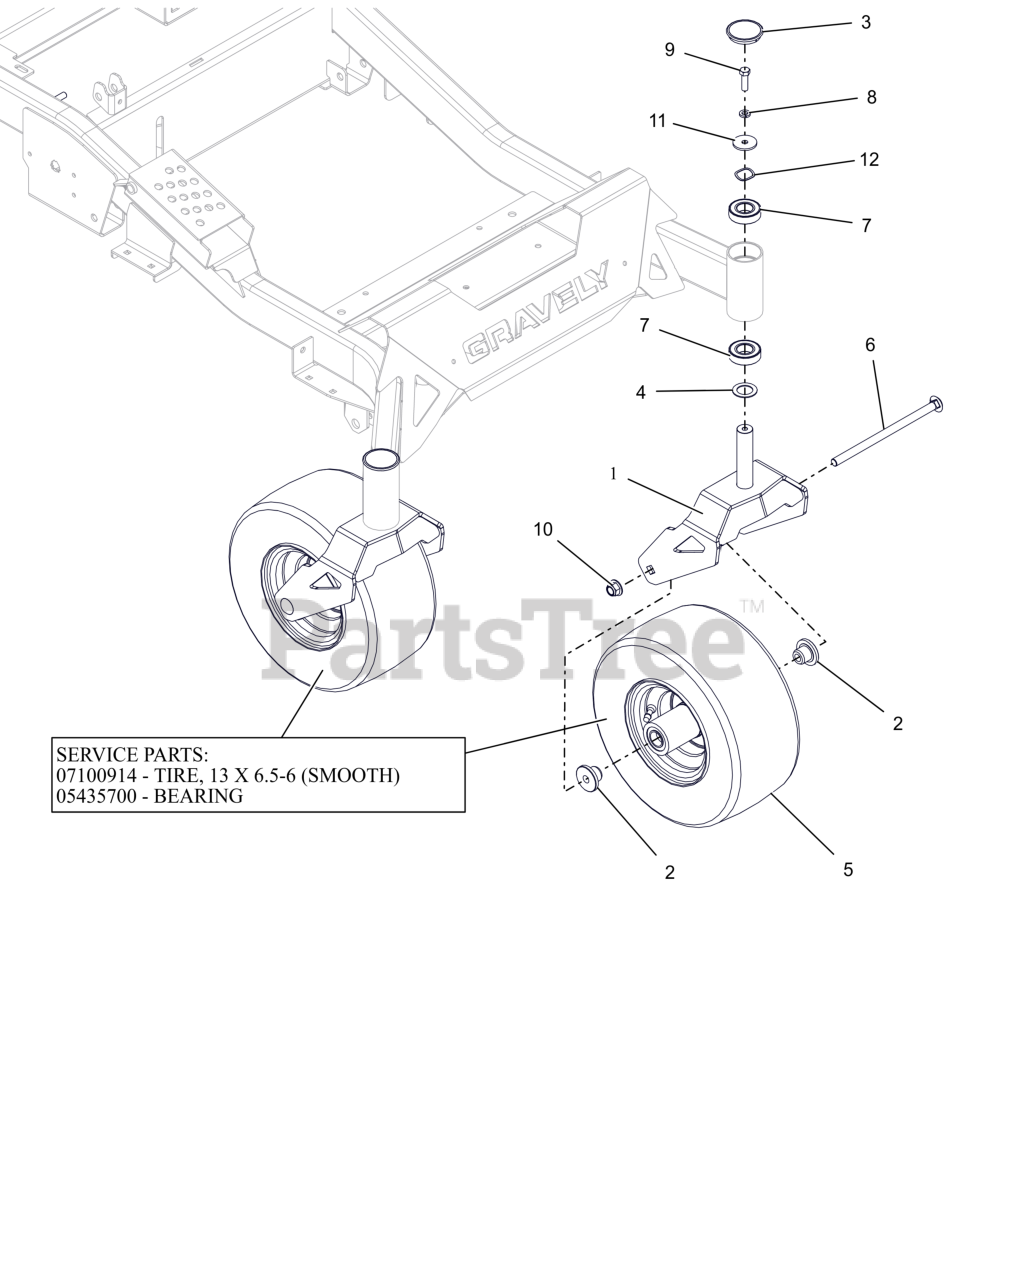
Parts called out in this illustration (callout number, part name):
1	WLDMT, CASTER FORK-HD (RED)
2	SPACER, FRONT WHEEL
3	CAP, DUST
4	WSHR-HRD-THRS 1.007X1.542X.062
5	ASM, WHL/TIRE 13X6.50-6
5	TIRE, 13X6.50-6 SMOOTH
5	BRG, 25MM ID X 52MM OD X 15MM
6	BTL,RHSN .500-13 X 9 G5 ZCC
7	BRG,BALL 1.00X2.00X.563(1641)
8	WSHR, LK-HVY .375X.115 ZCC
9	BLT, HEX .38-16X1.25 G5 ZCC
10	NUT,NYL-FLG .50-13 GF ZCC
11	WSHR, FLT .380X1.50X.125 ZCC
12	WSHR-WAVE 1.0X1.25X.028 .145FH
